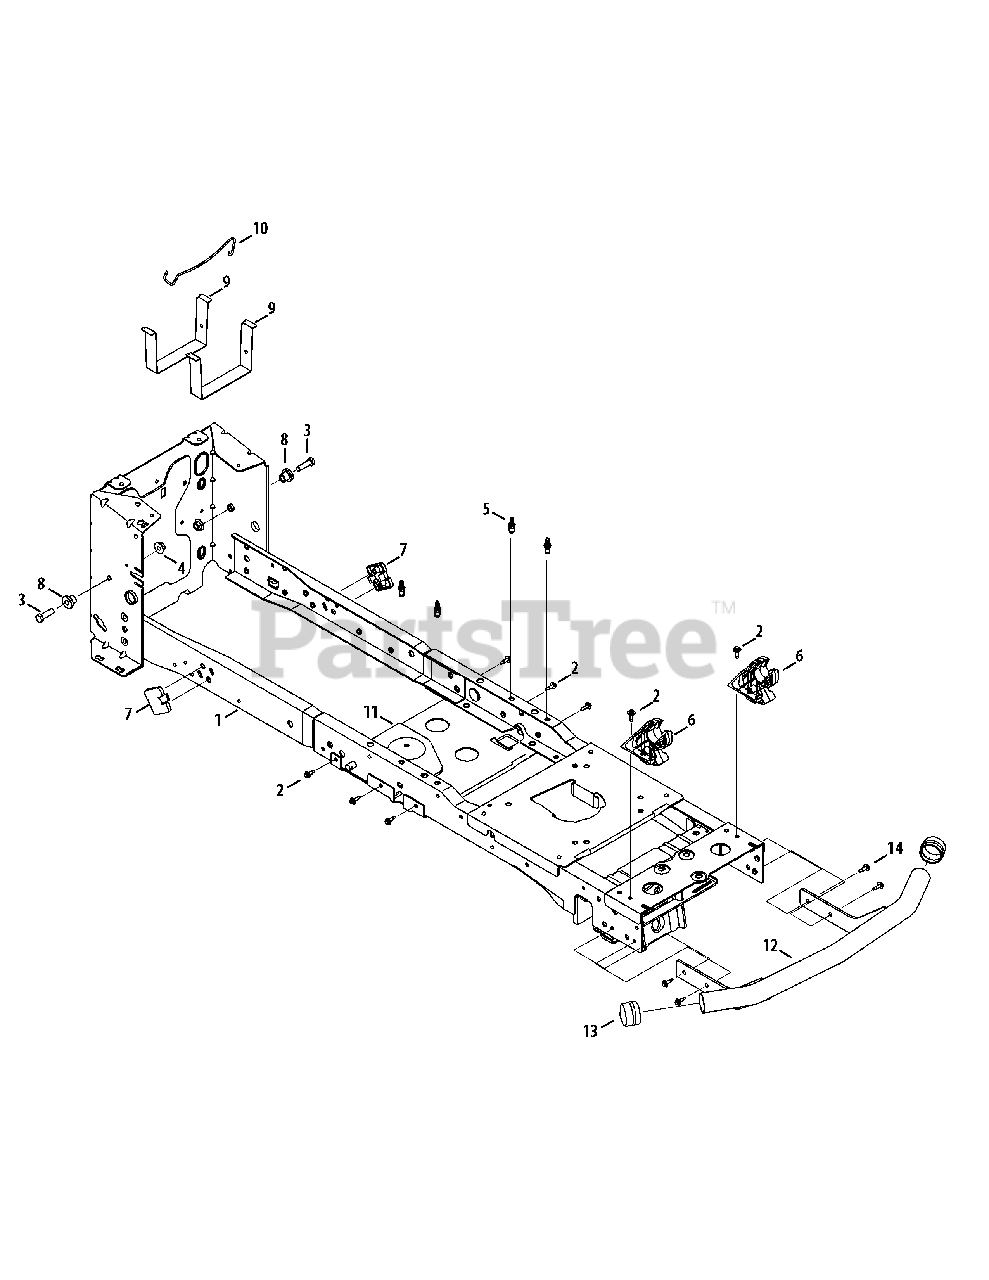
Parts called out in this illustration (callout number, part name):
1	Frame Assembly
2	Screw, M6-1 x .625
3	Hex Cap Screw, 3/8-16 x 1.25
4	Flange Lock Nut, 3/8-16
5	Rivet, 1/4-20 x .750
6	Pivot Bracket
7	Wear Pad
8	Shoulder Spacer, .38 x 1.0 x .70
9	Battery Bracket
10	Rod, Battery
12	Bumper Assenbly
13	Hub Cap
14	Hex Flange Screw, 3/8-16
